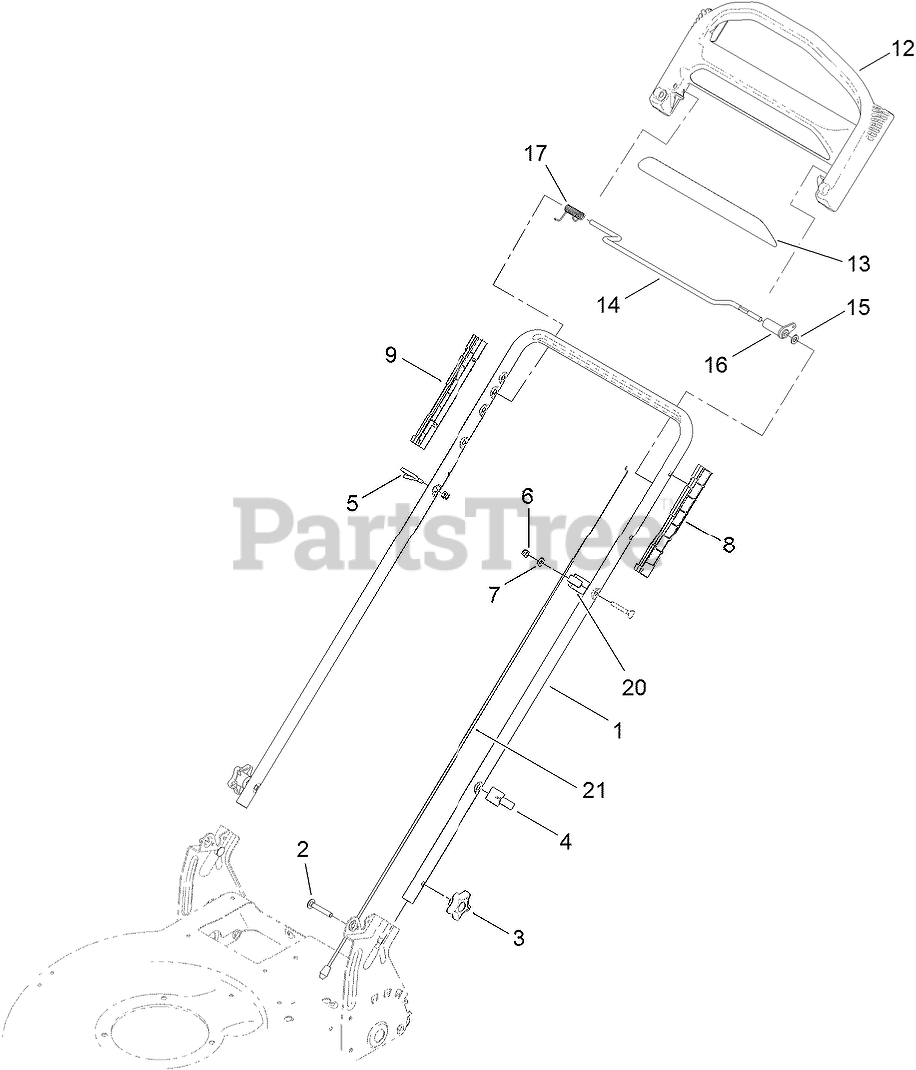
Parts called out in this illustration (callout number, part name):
2	Screw-CARR
3	KNOB-HANDLE
4	GUIDE-CABLE
5	GUIDE-ROPE
6	NUT-LOCK, NI
7	WASHER-FLAT
8	GUIDE-LH
9	GUIDE-RH
12	HANDLE-CONTROL
13	DECAL-HANDLE
14	BAR-CONTROL, TRACTION
15	WASHER-PLAIN
16	LEVER-TRACTION
17	Spring-Torsion
20	ANCHOR-CABLE
21	CABLE-TRACTION
